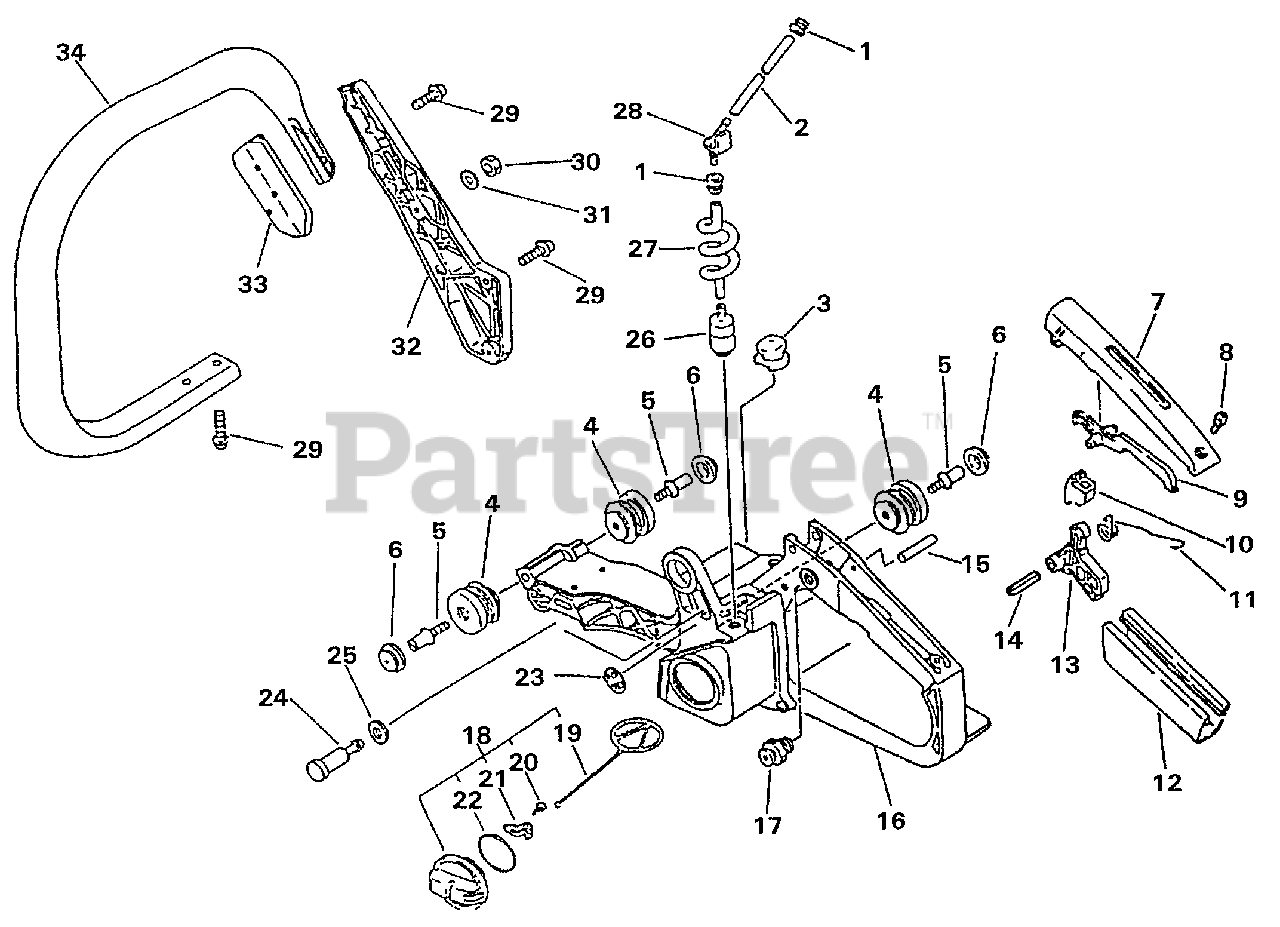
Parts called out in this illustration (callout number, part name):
1	GROMMET
2	PIPE, FUEL - 3×6×100
4	CUSHION
6	CAP, CUSHION
7	COVER, HANDLE
8	SCREW 4×14
9	LEVER, THROTTLE LOCKOUT
10	CUSHION, THROTTLE
11	SPRING, THROTTLE RETURN
13	TRIGGER, THROTTLE
14	PIN, SPRING Ø5×25 MM
15	PIN 3×26
16	HANDLE - REAR
17	LOCK, THROTTLE
18	CAP ASSY
19	CONNECTOR, CAP L= 60 MM
20	SCREW, TAPPING 3×8
21	RETAINER, CONNECTOR
22	O-RING 29
23	CUSHION (B)
24	VENT ASSY
25	GROMMET, FUEL
26	FILTER, FUEL
27	PIPE - SPIRAL
28	CONNECTOR, PIPE
29	SCREW, TAPPING 5×20
30	NUT, SLOT 5
31	WASHER, FLAT 5.5×10×0.8
32	BRACKET, HANDLE
33	BRACKET, HANDLE
34	HANDLE, FRONT
